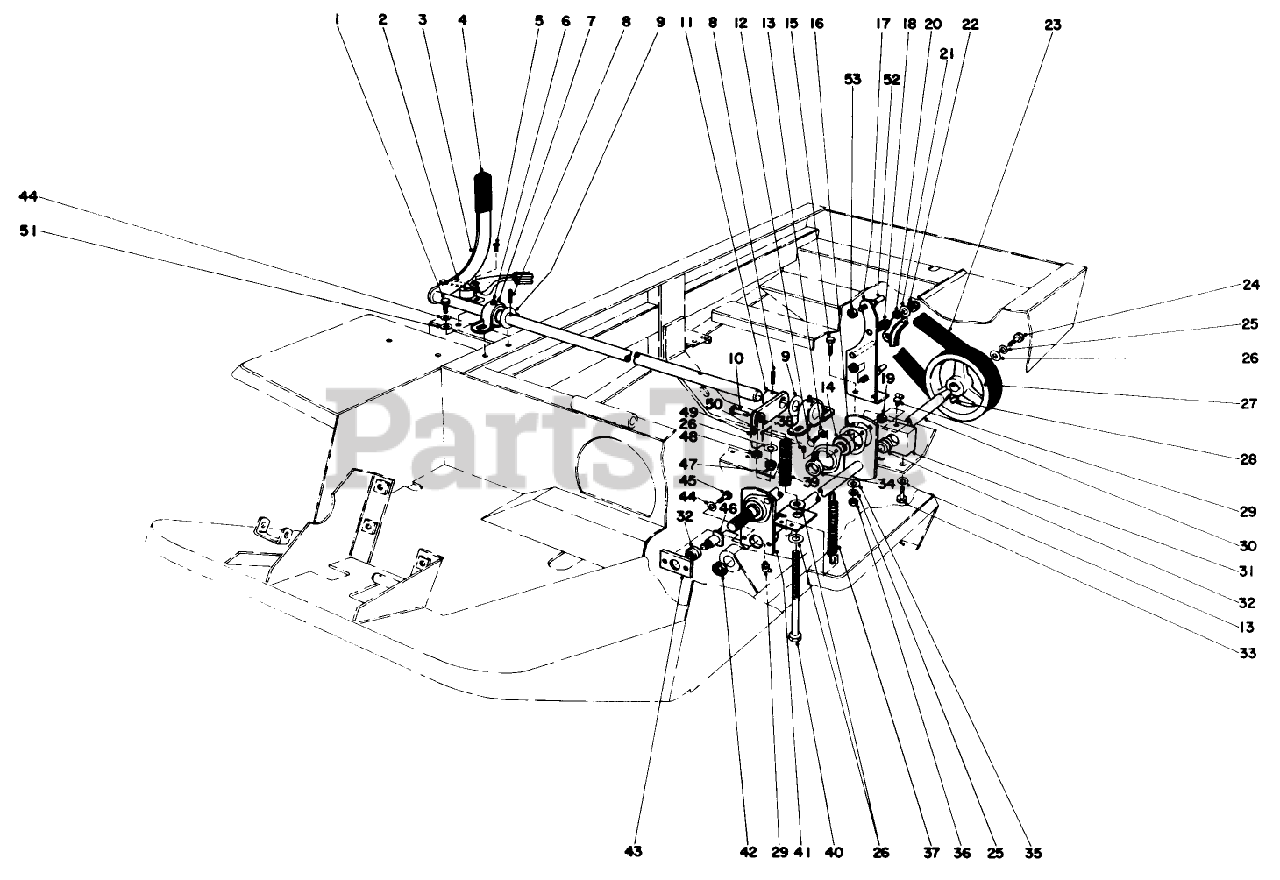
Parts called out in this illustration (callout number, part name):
1	SCREW-HH
2	Switch Power Take Off
3	P.T.0. Lever
4	GRIP-HANDLE
5	SCREW-THD FRM,HWH
6	FITTING-GREASE
7	Bearing
8	PIN-SPRING
9	THRUST WASHER
10	PIN-CLEVIS
11	ENGAGE ARM WA
12	SCREW-CARR
13	WASHER-LOCK
14	Bearing (Incl. Ref. #34 & 38)
15	SCREW-HH
16	FLANGE
17	PTO BRAKE BRKT WA BO
18	COMP SPRING O
19	NUT-HEX
20	Brake Shoe & Lining Assembly
21	WASHER-FLAT
23	V-Belt A Section
24	SCREW-HH
25	WASHER-LOCK
26	WASHER
27	PULLEY-PTO, MACH.
28	KEY-WOODRUFF
29	FITTING-GREASE, 90 DEG
30	PTO SHAFT
31	Bearing Hub
32	BEARING
33	SCREW-HH
34	COLLAR-LOCK, BEARING
35	WASHER-FLAT
36	NUT-HEX
37	SPRING-EXTENSION
38	SCREW-SET, HSH
39	SPRING-COMPRESSION
40	SCREW-ADJUSTING
41	Engagement Arm
42	NUT-LOCK, NI
43	BRG RETAINER
44	WASHER-LOCK
45	SCREW-HH
46	BEARING STUD
47	NUT-HEX
48	NUT-HJ
49	Yoke
50	PIN-COTTER
51	WASHER-FLAT
52	PTO BELT GUIDE
53	NUT-JAM
